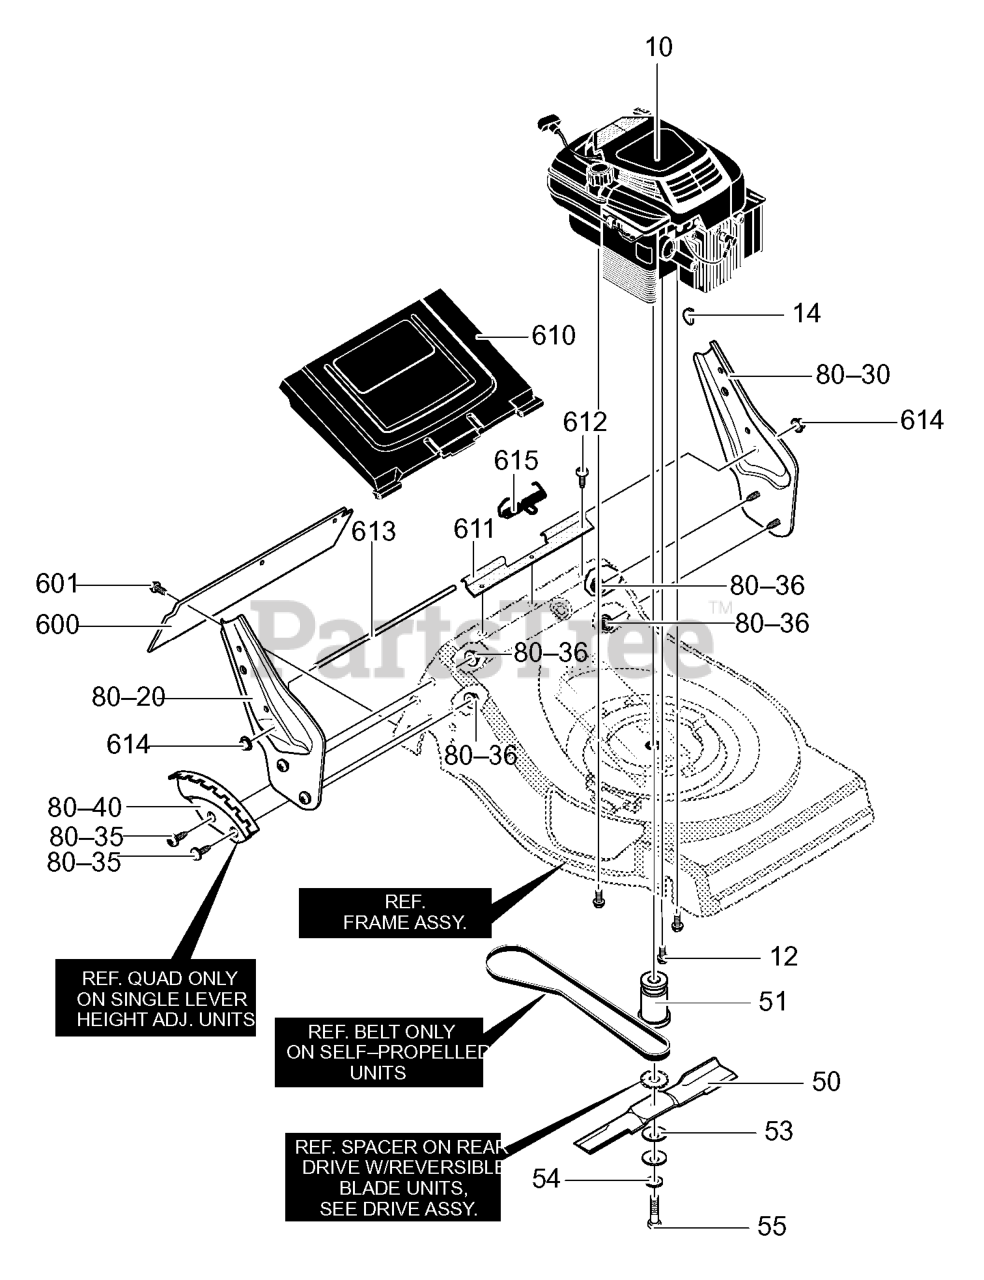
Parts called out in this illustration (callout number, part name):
10	ENGINE *
12	SCREW, 3 /8-16X1.00
14	NOT USED ON THIS UNIT
50	BLADE, 21" MULCH
51	ADAPTER, BLADE 21"
53	WASHER, BEVELLE
54	WASHER, FLAT .406 x .812 x .06
55	SCREW, 3/8-24 x 1.50
80-20	BRACKET, HANDLE RH
80-30	BRACKET, HANDLE LH
80-35	SCREW, 5/16-18 x 0.63
80-36	NUT, 5/16-18, HEXWDFLK WHIZ
80-40	QUADRANT, HEIGHT ADJ
600	DEFLECTOR, REAR
601	SCREW, 10-16X.50
610	DOOR, REAR 21
611	SPACER,RR DOOR
612	SCREW, 10-16X.50
613	ROD, PIVOT RR DOOR.25X18.5
614	CAP, PUSH ON
615	SPRING, TORSION
